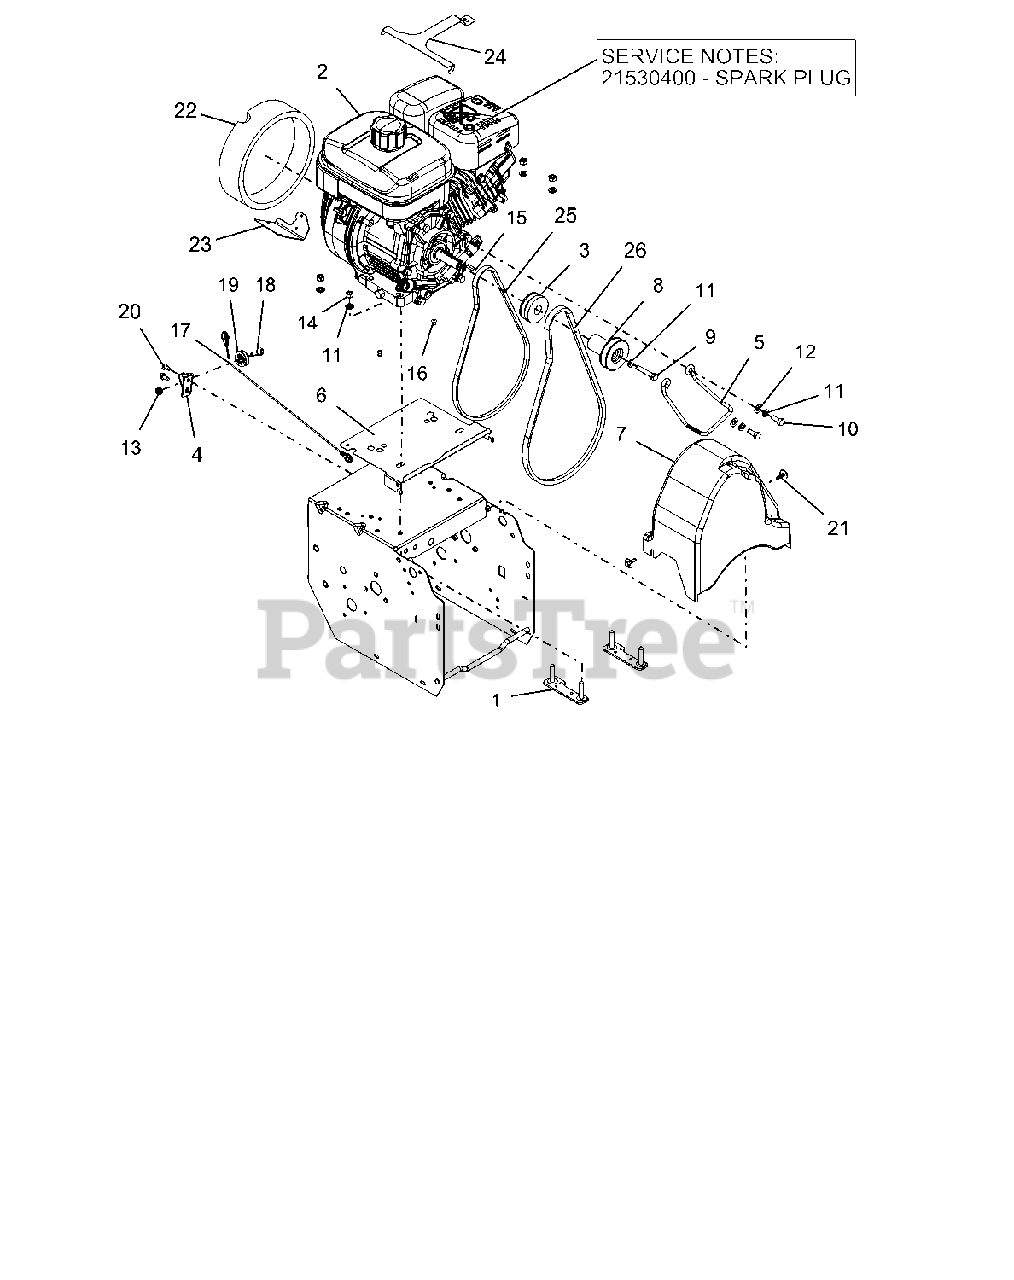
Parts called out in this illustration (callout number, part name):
1	STRAP, ENGINE BOLT-WELDMENT
2	PLUG, SPARK - TEC. SNO-THRO
2	SUBARU EX17 120V ALL-SEASON
3	PULLEY, TRACTION
4	BRACKET, CABLE PULLEY
5	BELT FINGER
6	BAFFLE, COMPACT
7	BELT COVER
8	SHEAVE, AUGER DRIVE
9	BLT-HEX .31-24X1.75 GR5 YWZC
10	BLT-HEX .31-24X.75 YWZC GR5
11	WSHR-LK .312X.097 HVY YWZC
12	WSHR-FL-STL.344X.688X.065YWZC
13	NUT-LK-CTR-FLG .25-20 YWZC
14	NUT-HEX .31-18 YWZC
15	KEY-SQ .188X.75X.188
16	RVT-POP .187 YZ
17	CABLE, LOWER TRACTION (DELUXE)
18	BOLT, SHLDR-.375X.375X.25-20
19	PULLEY, CABLE
20	SCR-TAP .25-20X.50 HWH TR YWZ
21	SCR-TAP .25-20X.5 CAPTIVE
22	FOAM COVER, RECOIL-SUBARU
23	BRACKET, SWITCH-SUBARU
24	GUARD, SNOW-SUBARU EX17
25	V-BELT, 3L-WRAPPED
26	V-BELT, HA-RAW EDGE
